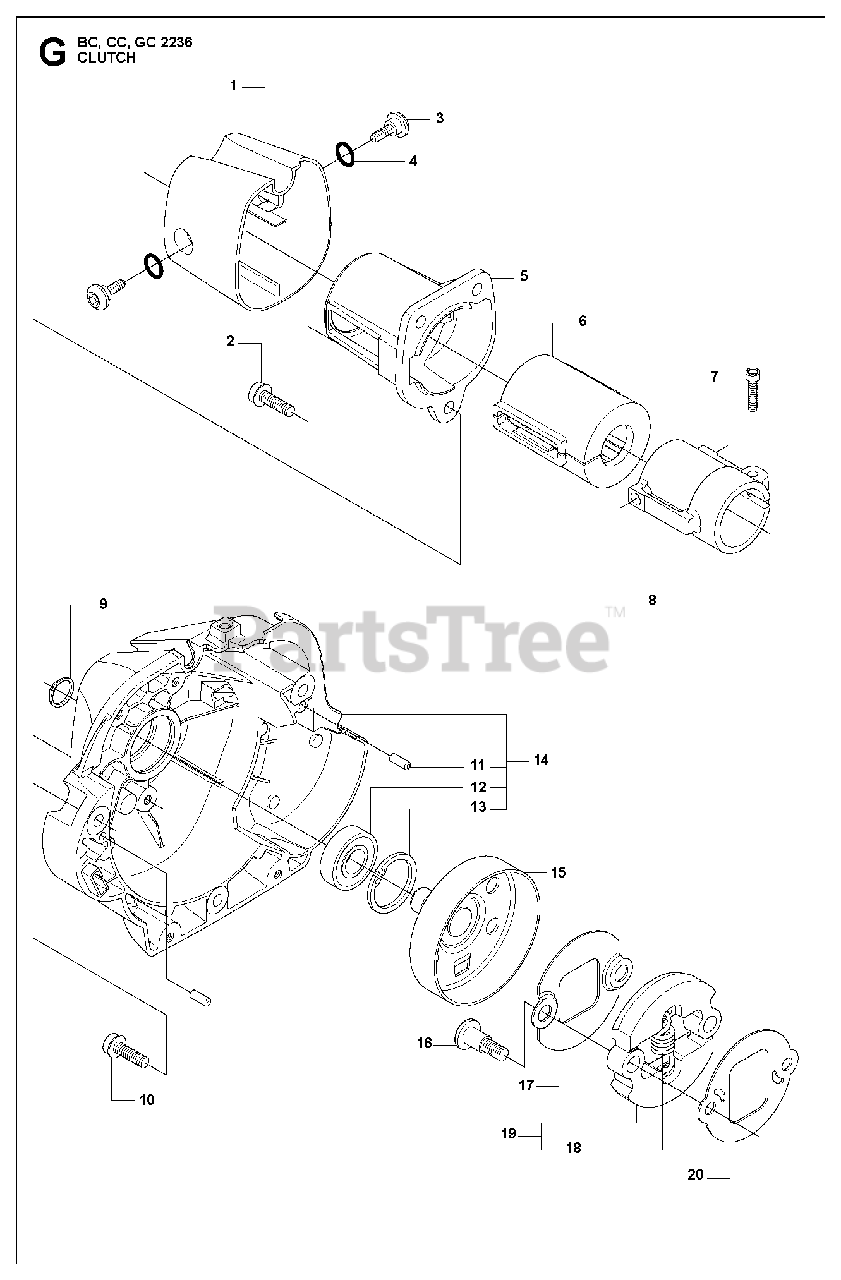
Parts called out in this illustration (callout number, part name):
1	COVER
3	SCREW MT5X11
4	O-RING 8X1.6
5	HOLDER, TUBE
6	VIBRATION ABSORBER
7	SCREW MC6S 5X25
8	SLEEVE, COVER
8	LOCKING SLEEVE
9	SEEGER CLIP
11	PIN
12	BALL BEARING
13	RETAINING RING SGH 28
15	CLUTCH DRUM
16	SCREW CLUTCH
18	SPRING
19	CLUTCH CPL
20	WASHER
